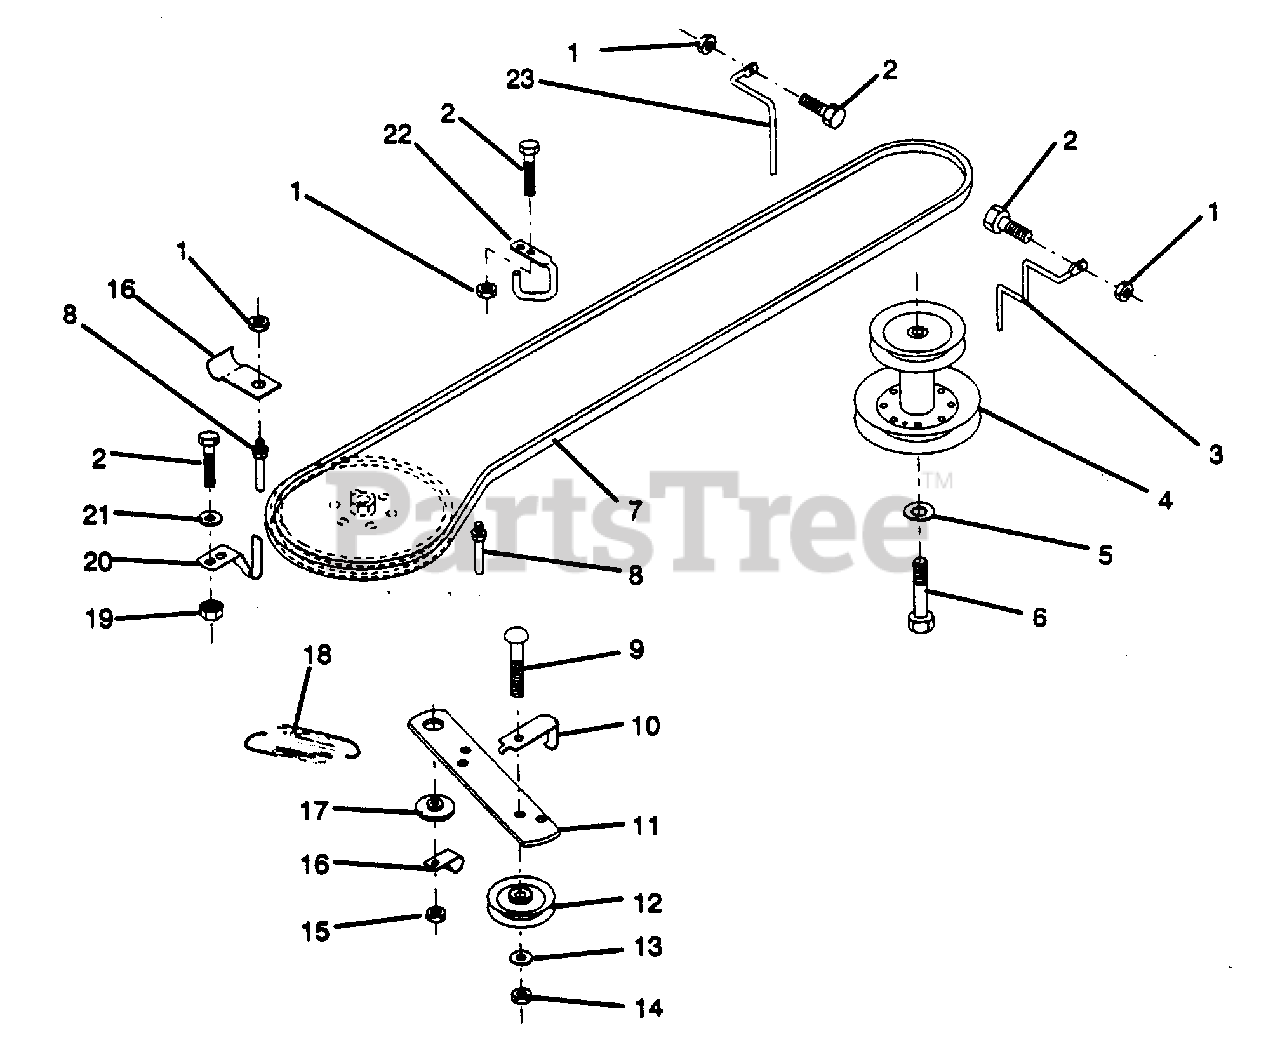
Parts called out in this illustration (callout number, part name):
1	Nut, Crownlock 5/16-18
2	Bolt, Hex Hd. 5/16-18 UNC x 3/4 (AYP part number)
3	Keeper, Engine Mower Drive R.H. Belt (AYP part number)
4	Pulley, Engine (AYP part number)
5	Washer, Lock Hvy. Helical Spring 7/16 (AYP part number)
6	Bolt, Fin. Hex 7/16-20 UNF x 1-1/4 Gr. 8 (AYP part number)
7	Traction, V-Belt Drive (AYP part number)
8	Keeper, T/A Ground Drive Belt (AYP part number)
9	Bolt, Carriage 3/8-16 UNC x 1-1/2 (AYP part number)
10	Keeper, Belt Ground Drive Idler (AYP part number)
11	Arm, Ground Drive Clutch (AYP part number)
12	Idler, Flat (AYP part number)
13	Washer 13/32 x 13/16 x 16 Ga. (AYP part number)
14	Nut, Centerlock 3/8-16 UNC (AYP part number)
15	Nut, Crownlock 3/8-16 UNC
16	Clip, Insulated (AYP part number)
17	Spacer, Retainer (AYP part number)
18	Spring, Extension (AYP part number)
19	Nut, Keps 5/16-18 UNC (AYP part number)
20	Keeper, T/A Ground Drive Belt (AYP part number)
21	Washer 11/32 x 5/8 x 16 Ga. (AYP part number)
22	Keeper, Frame Ground Drive Belt (AYP part number)
23	Keeper, Engine Mower Drive L.H. Belt (AYP part number)
